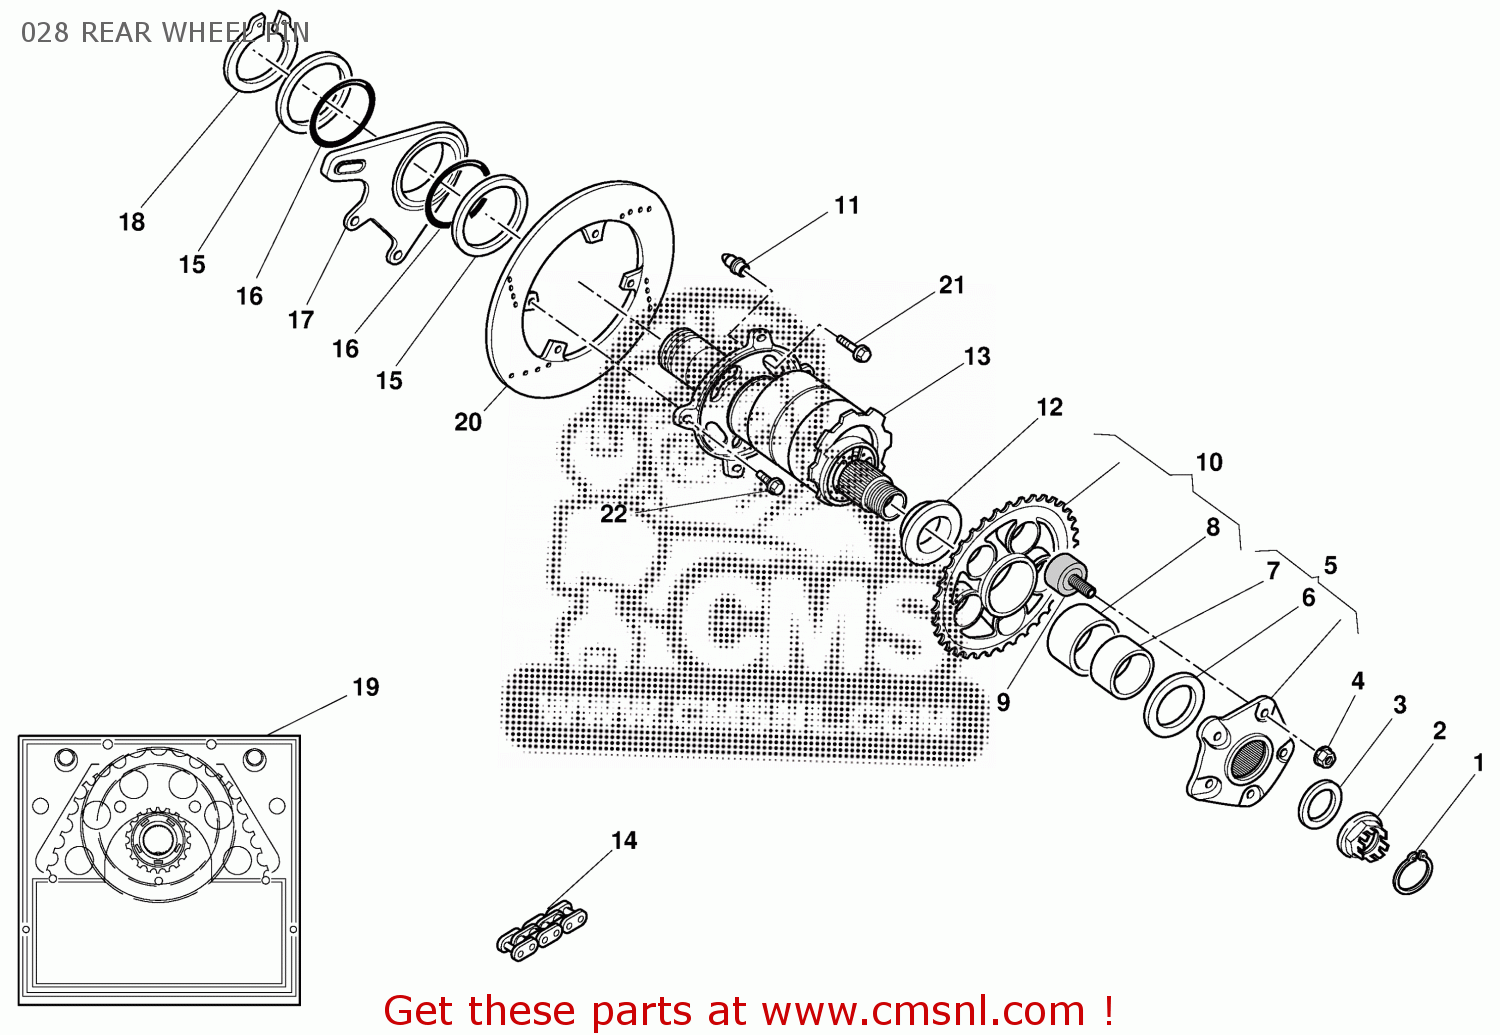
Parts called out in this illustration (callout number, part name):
1	RETAINER 35MM
2	NUT, CASTLE LH
3	WASHER
4	NUT, FLANGED M10
5	REAR SPROCKET FLANGE
6	WASHER
7	BUSH
8	BUSH
9	ABSORBER, HUB SHOCK
10	REAR SPROCKET T36
11	PIN
12	FINAL SPROKET SLEEVE
13	HUB, REAR WHEEL
14	CHAIN DID 525HV X 94
15	WASHER
16	O-RING
17	PLATE
18	CIRCLIP
19	FINAL DRIVE KIT
20	REAR BRAKE DISC
21	SCREW
22	SCREW M8X14
